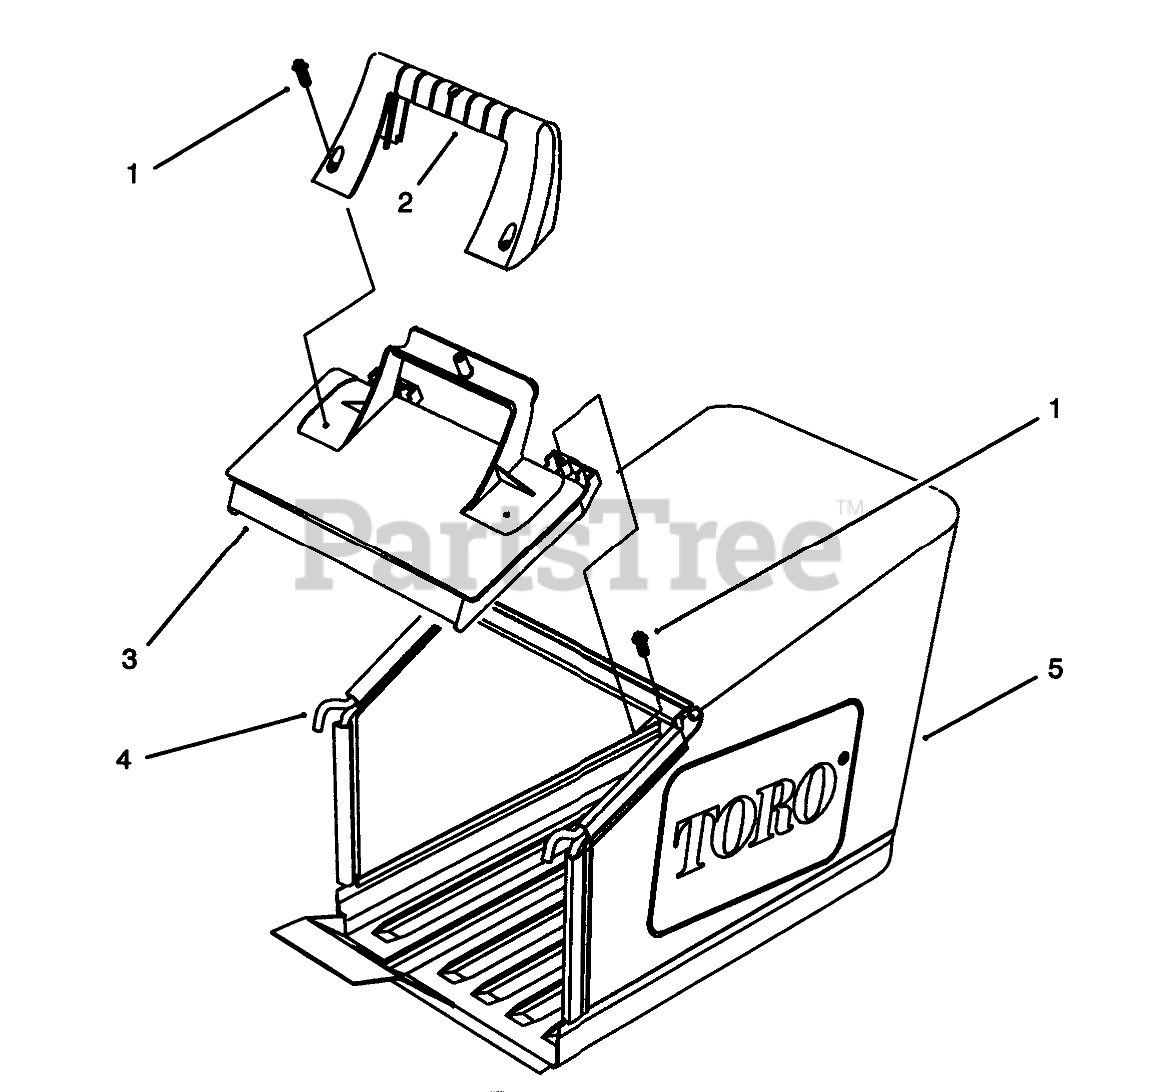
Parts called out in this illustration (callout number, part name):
1	SCREW-PPH
2	HANDLE-DOOR
3	DOOR-BAG
4	Frame
5	GRASS BAG 48CM W/PAN
